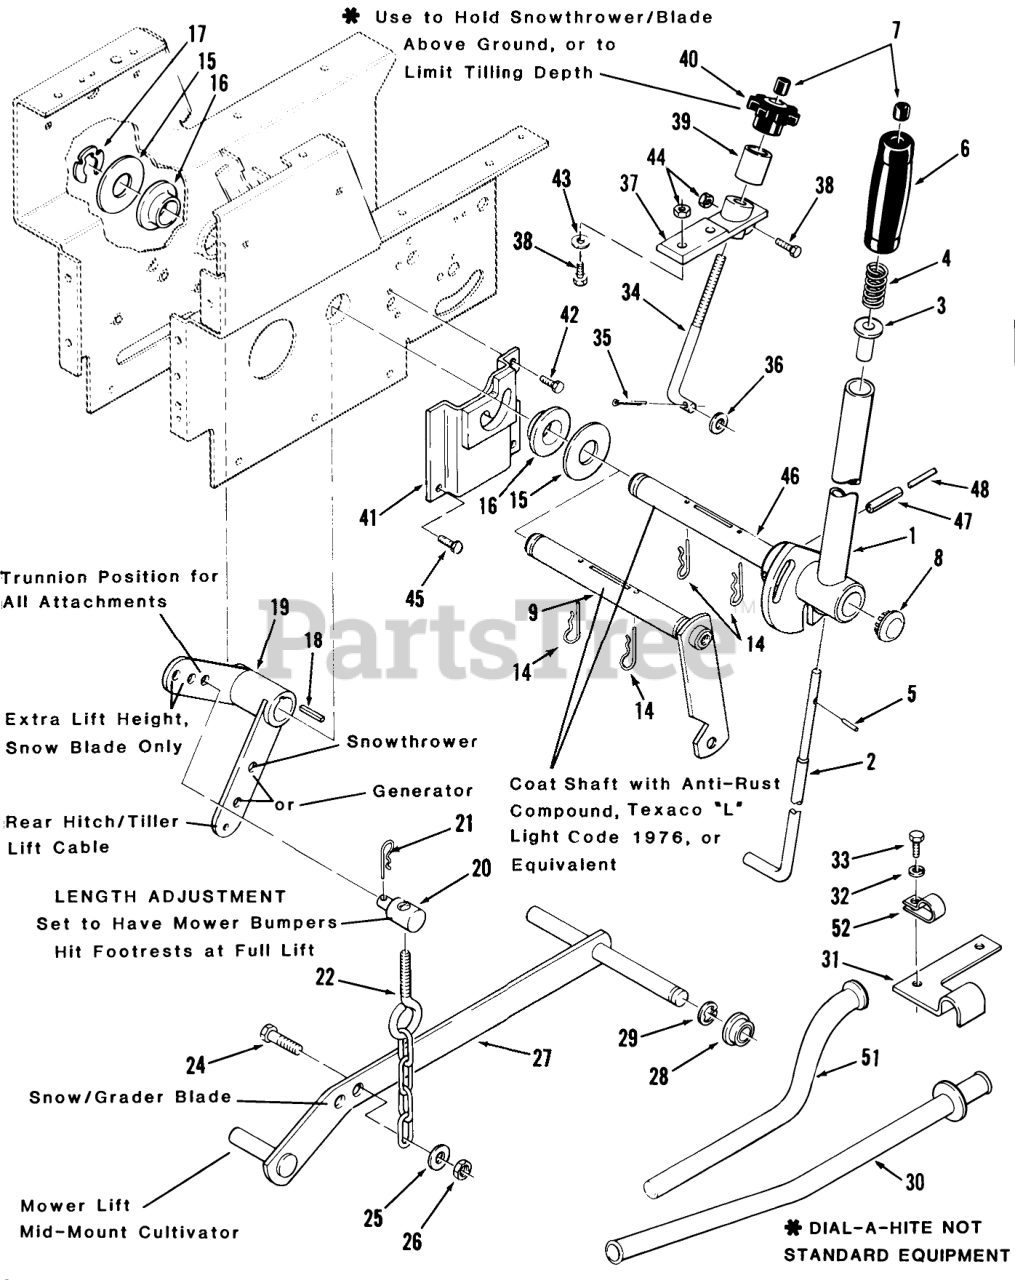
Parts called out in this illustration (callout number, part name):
1	Lift Lever (Includes Items 46, 47, 48)
2	ROD-LATCH LIFT
3	RETAINER-SPRING
4	SPRING-COMPRESSION
5	PIN-SPIROL
6	HANDGRIP
7	CAP-ROD, PLUNGER
8	PLUG
9	Lift lever
14	Pin-Cotter
15	WASHER
16	BEARING-FLANGE
17	Retainer
18	KEY-SQUARE
19	Bellcrank
20	TRUNNION
21	Hairpin
22	CHAIN-LIFT
24	Bolt
25	WASHER 5/16 SAE
26	Nut
27	ASSY LIFT BAR R
28	BUSHING
29	E Ring
30	TUBE ASSY COMPLET R
31	CLAMP-CONDUIT R
32	LOCKWASHER
33	Bolt
33	BOLT
34	Rod
35	Pop Rivet
36	WASHER -4
37	Casting
38	Bolt
39	Sleeve
40	KNOB-LIFT CONTROL
41	Latch Bracket
42	SCREW
43	WASHER 5/16 SAE
44	Nut
45	Bolt
46	SHAFT-LIFT LEVER
47	SPIROL PIN
48	Roll Pin
51	TUBE-CONDUIT R
52	CLIP
